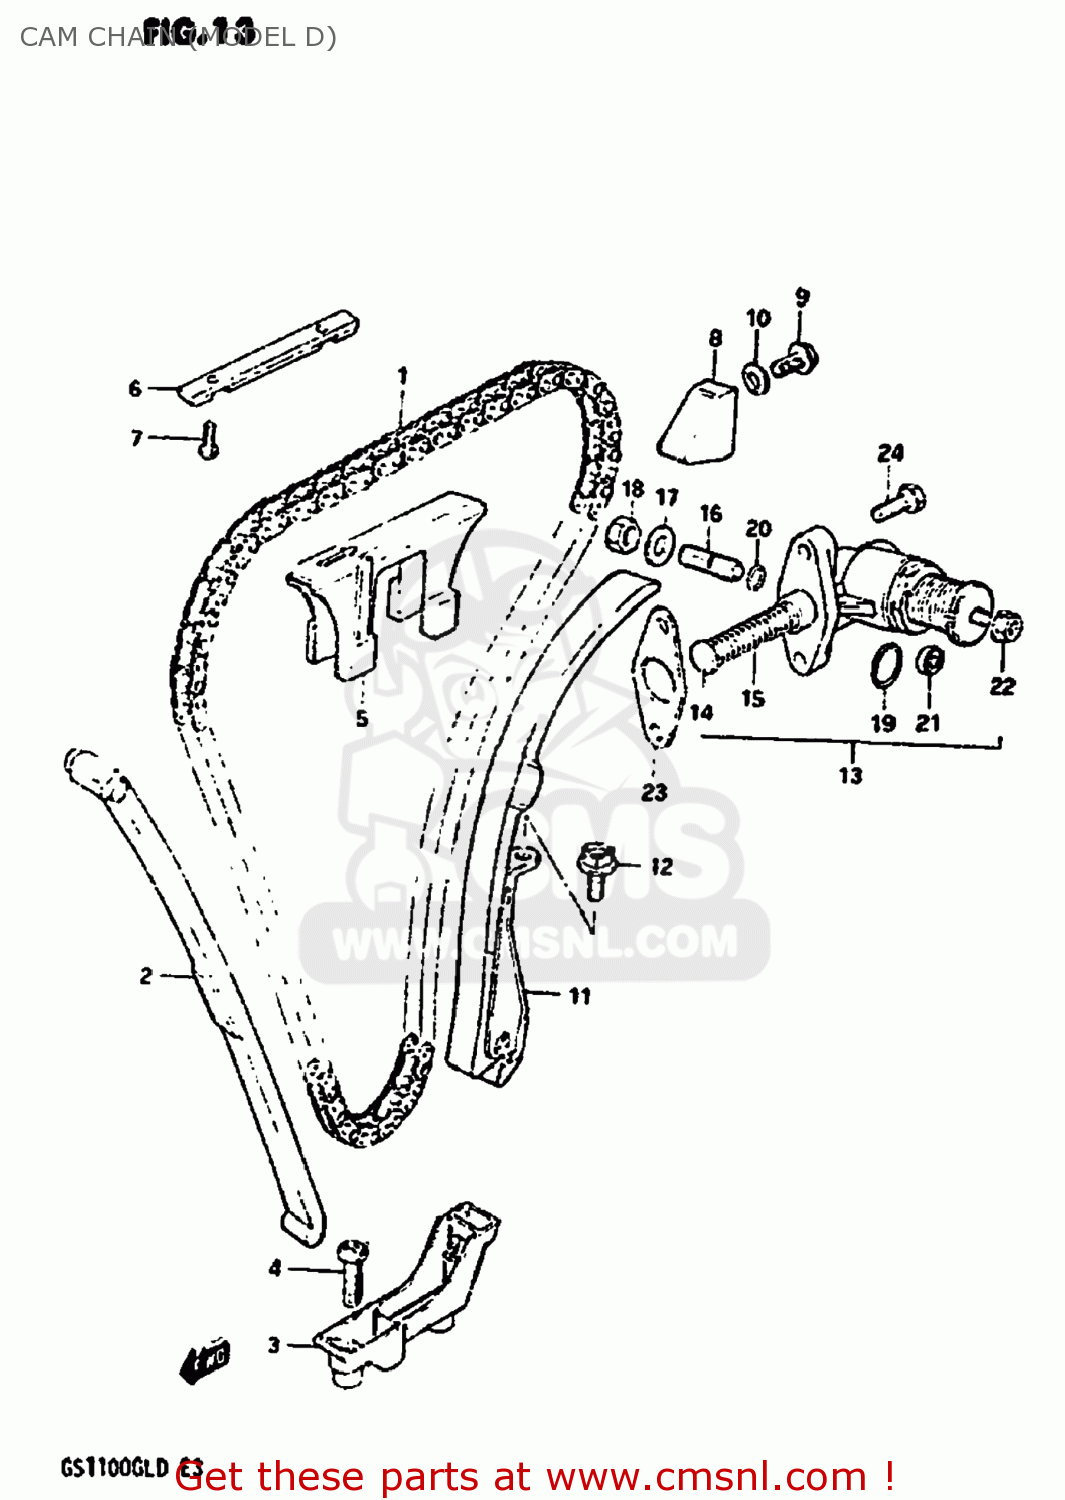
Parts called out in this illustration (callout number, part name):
1	CHAIN,CAMSHAFT DRIVE
2	GUIDE,CAM CHAIN NO.1
3	HOLDER,CAM CHAIN GUIDE
4	SCREW
5	GUIDE,CAM CHAIN NO.2
6	GUIDE,CAM CHAIN
7	SCREW
8	GUIDE,CAM CHAIN
9	BOLT 6X12
10	GASKET (NAS)
11	TENSIONER,CAM CHAIN
12	BOLT
13	ADJUSTER ASSEMBLY,TENSIONER
14	ROD,PUSH
15	SPRING
16	SCREW,TENSIONER ADJUST
17	WASHER,8.5X16X
18	NUT
19	O RING(D:2.4,ID:20.8)
20	O RING(D:1.9,ID:5.7)
21	SEAL,OIL(10X16X4)
22	NUT
23	GASKET,TENSIONER ADJUSTER (MCA)
24	SCREW (6X25)
